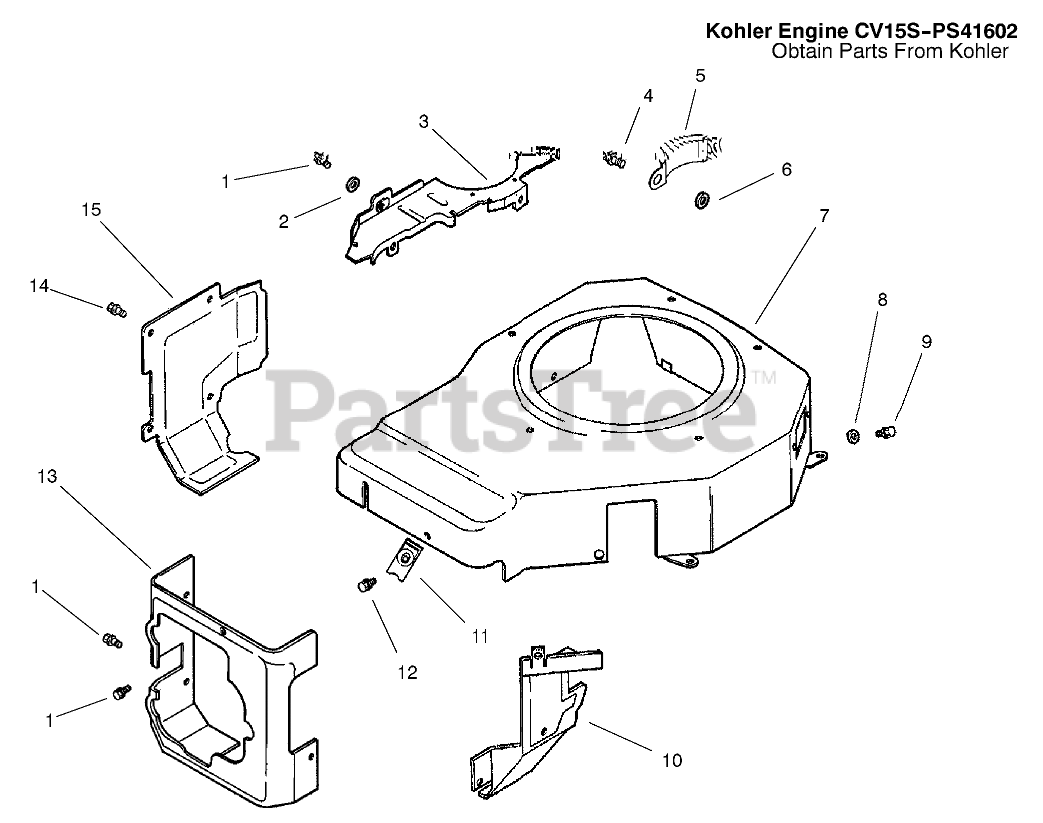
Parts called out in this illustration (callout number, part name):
1	Screw (M5x0.8x10)
2	Washer
3	Plate-Blower Housing
4	Screw-HHF
5	Cover-Pinion
6	Washer
7	Housing-Blower
8	Washer
9	Screw
10	Baffle-Carburetor
11	Clip
12	Screw M5x0.8x20
13	Baffle-Cyl. Head
14	Screw-Hex, Flange
15	Baffle-Cylinder
